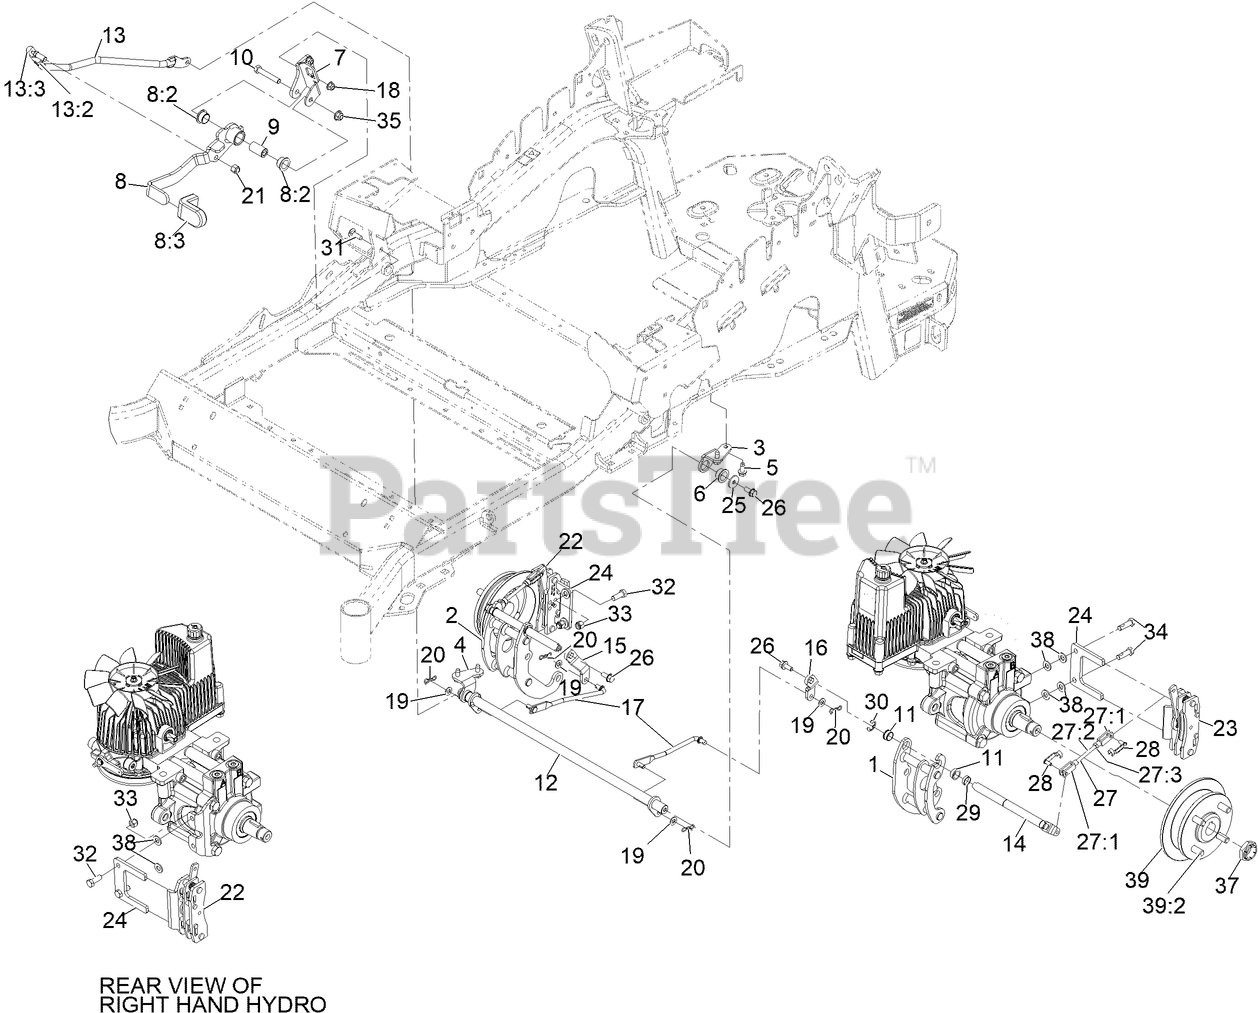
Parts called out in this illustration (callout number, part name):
1	MOUNT-BELLCRANK, LH
2	MOUNT-BELLCRANK, RH
3	MOUNT-PIVOT, LH
4	MOUNT-PIVOT, RH
5	Screw-HWH 5/16-18 X 3/4 Tf
6	BUSHING-FLANGE
7	BRACKET-MOUNT
8	Brake Lever ASM
8:2	BUSHING-FLANGE
8:3	GRIP-LEVER
9	HANDLE-PIVOT, BRAKE
10	SCREW-HH
11	BUSHING
12	Shaft-Cross
13	ASM, Front Linkage
13:2	END-TIE ROD, RH
13:3	NUT-HJ
14	BELLCRANK
15	ARM-INNER, RH
16	ARM-INNER, LH
17	MID-LINK, LONG
18	NUT-HF, NI
19	WASHER-PLAIN
20	PIN-COTTER, LOCKING
21	NUT-LOCK
22	Caliper-Brake, RH
23	Caliper-Brake, LH
24	PLATE-MOUNT, BRAKE
25	WASHER-FLAT
26	SCREW-HHF
27	REAR LINKAGE ASM
27:3	NUT-JAM
28	PIN-CLEVIS, SPRING
31	BOLT-CARR
32	SCREW-HH,
33	NUT-LOCK
34	Screw-HH, Patch
35	NUT-HF, NI
37	LOCKNUT
38	WASHER-FLAT
39	Wheel Hub ASM
39:2	STUD-WHEEL
